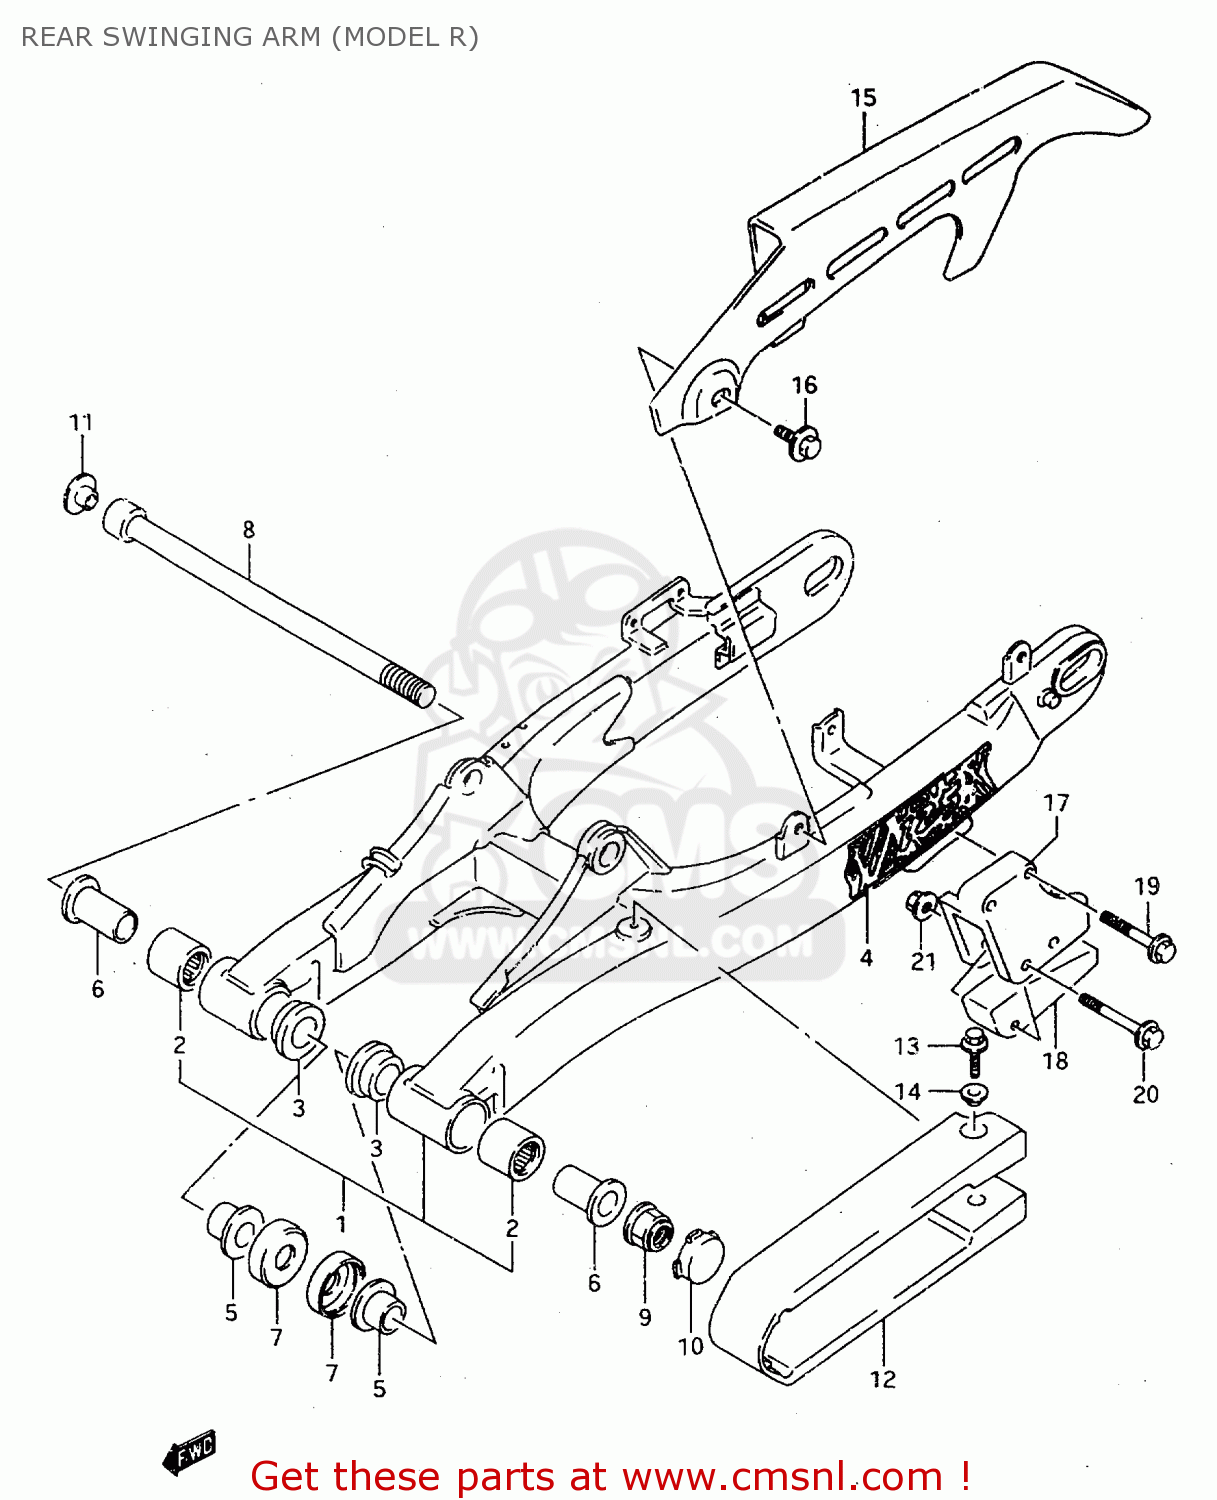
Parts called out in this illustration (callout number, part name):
1	SWINGING ARM ASSY, REAR
2	BEARING(20X27X30)
3	BUSH,RR SWINGINGARM PIVOT
4	EMBLEM, 125
5	SPACER,RR SWGARM PIVOT INNER
6	SPACER,RR SWGARM PIVOT
7	COVER,RR SWGARM DUST SEAL
8	SHAFT, PIVOT
9	NUT
10	CAP,PIVOT
11	CAP,SHAFT
12	BUFFER,CHAIN TOUCH DEFENSE
13	BOLT
14	WASHER
15	CASE,CHAIN
16	BOLT 6X8
17	GUIDE,CHAIN
18	DEFENSE,CHAIN GUIDE
19	BOLT
20	BOLT,UNDER
21	NUT
22	EMBLEM, SUZUKI
